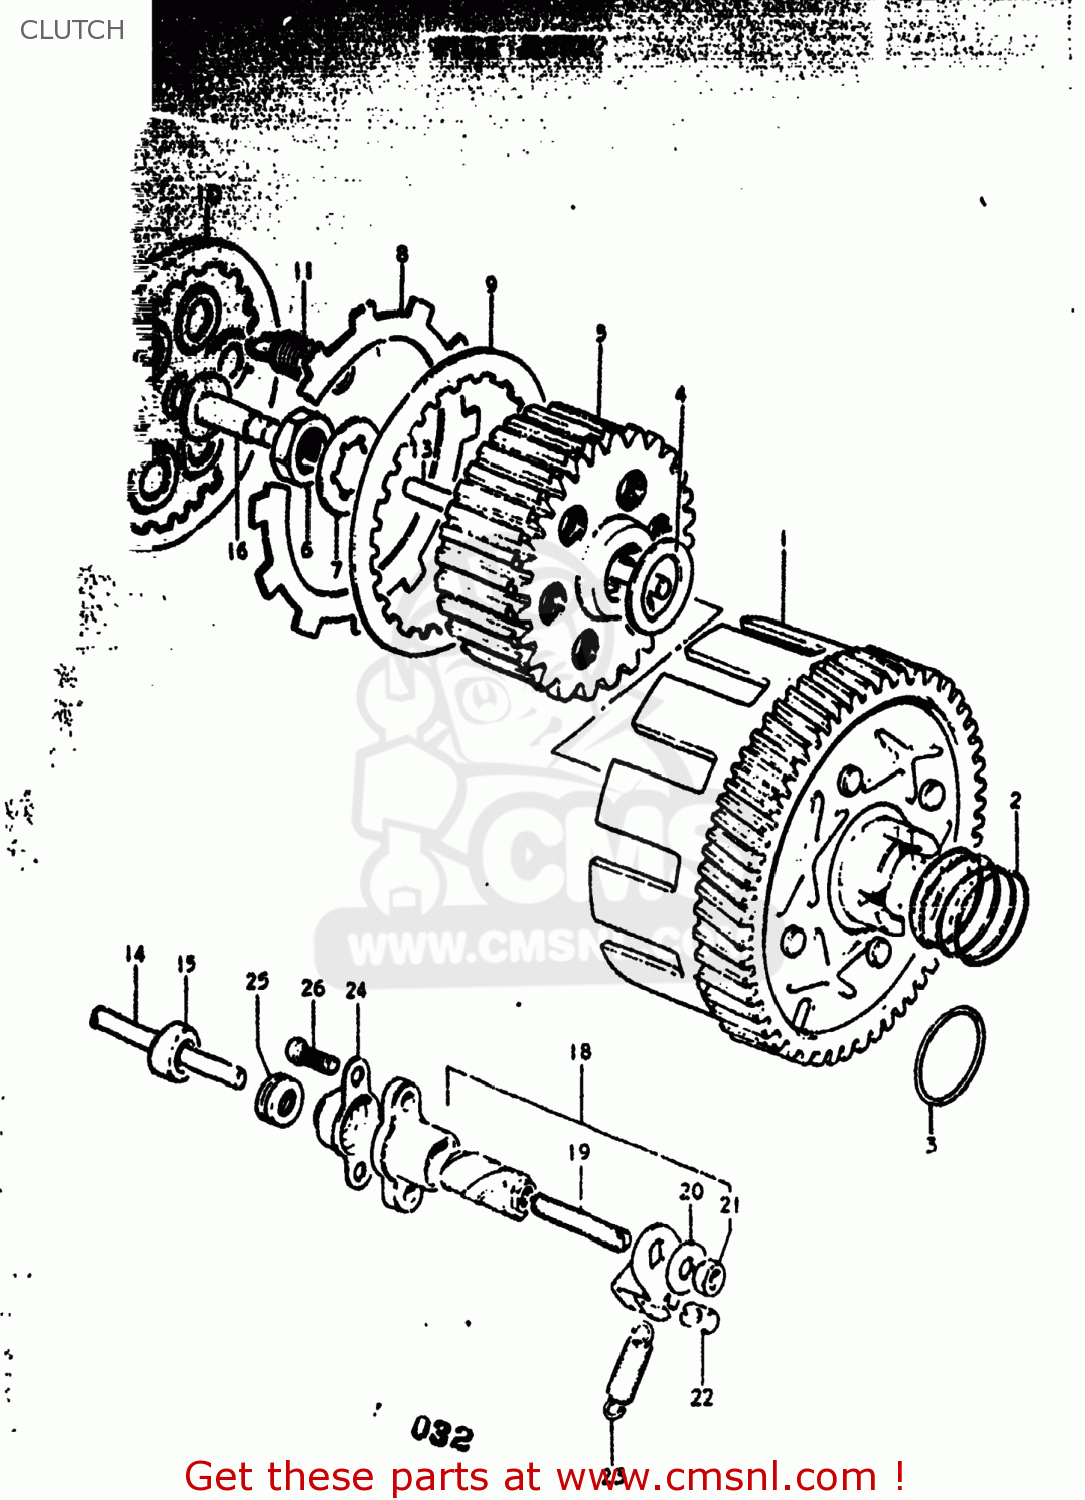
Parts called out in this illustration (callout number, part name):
1	GEAR ASSEMBLY,PRIMARY DRIVE
2	SPRING
3	SPRING
4	WASHER
5	HUB,CLUTCH SLEEVE
6	NUT
7	WASHER,LOCK
8	PLATE,CLUTCH DRIVE (MCA)
9	PLATE,CLUTCH DRIVEN (NAS)
10	PLATE,CLUTCH PRESSURE
11	SPRING
12	PIN(2.5X19.8)
13	ROD,CLUTCH PUSH
14	ROD,CLUTCH PUSH
15	SEAL,OIL(5.5X16X8)
16	ROD,CLUTCH RELEASE
17	SEAL,OIL (10X17X5)
18	SCREW ASSY,CLUTCH RELEASE
19	SCREW
20	WASHER(6.5X16X1.2)
21	NUT
22	PIECE,RELEASE ARM END
23	SPRING
24	COVER,CLUTCH RELEASE SCREW
25	SEAL,DUST(5.3X13X5)
26	SCREW
